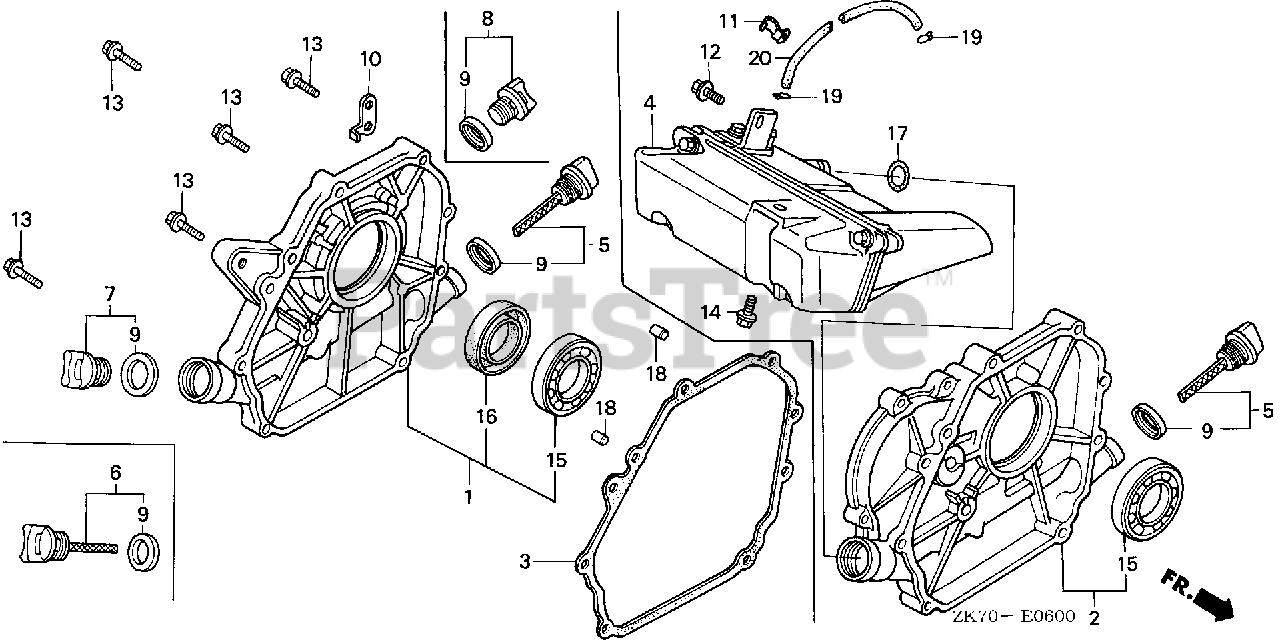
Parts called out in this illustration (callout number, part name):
1	COVER ASSY., CRANKCASE
3	GASKET, CASE COVER
5	CAP ASSY., OIL FILLER (GRAY)
7	CAP ASSY., OIL FILLER
9	GASKET, OIL FILLER CAP
13	BOLT, FLANGE (6X28) (CT200)
15	BEARING, RADIAL BALL
16	OIL SEAL (22X41X6)
18	PIN, DOWEL (8X14)
